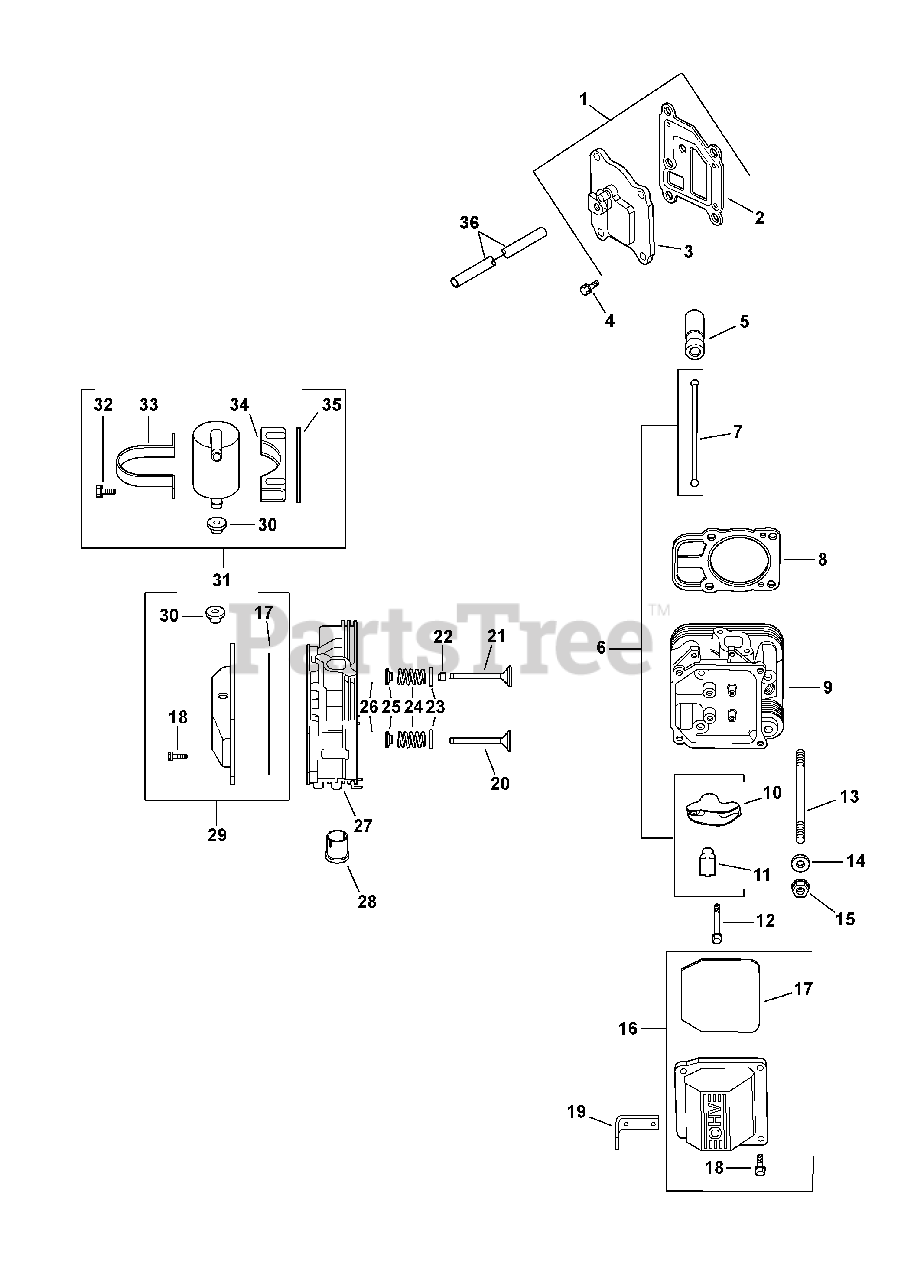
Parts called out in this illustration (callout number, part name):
1	Breather Cover Kit w/ Gskt. (Inc. 2 & 3)
2	Breather Gasket
3	Breather Cover
4	Flange Screw, M6 x 1.0 x 20
5	Hydraulic Valve Lifter Kit
6	Valve Train Kit (Inc. 7, 10 & 11)
8	Cylinder Head Gasket Kit
9	#2 Cylinder Head Assembly Kit
11	Rocker Arm Pivot
12	Flange Screw, M6 x 1.0 x 34
13	Stud, M8 x 1.25
14	Flat Washer, 8.6 mm
15	Flange Nut, M8 x 1.25
16	Plain Rocker Cover Kit (Inc. 17 & 18)
17	Valve Cover O-Ring
18	Flange Screw, M6 x 1.0 x 30
19	Lifting Strap
20	Exhaust Valve (STD)
20	Exhaust Valve (.25)
21	Intake Valve (STD)
21	Intake Valve (.25)
22	Valve Stem Seal
23	Spring Retainer
24	Valve Spring
25	Valve Spring Cap
26	Retainer Kit
27	#1 Cylinder Head Assembly Kit
28	Exhaust Port Liner
29	Breather Rocker Cover Kit (Inc. 17,18 & 30)
30	Rubber Grommet
31	Breather Separator Kit (Inc. 30-35)
32	Flange Screw, M6 x 1.0 x 16
33	Breather Strap
34	Breather Separator Bracket
36	Breather Hose
